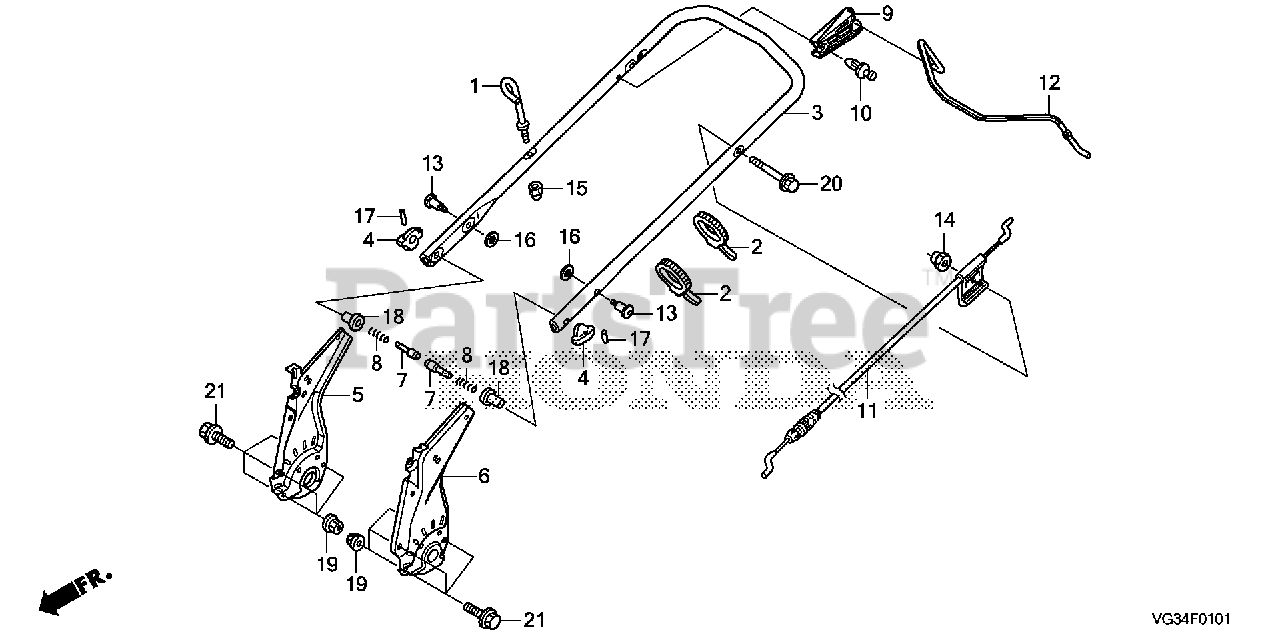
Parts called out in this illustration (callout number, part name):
1	GUIDE, ROPE
2	TIE, CABLE (157.5MM)
3	PIPE, HANDLE *NH105* (MAT BLACK)
4	GRIP, HANDLE JOINT *NH164* (GRIP GRAY)
5	STAY, R. HANDLE
6	STAY, L. HANDLE
7	PIN (8MM)
8	SPRING, HANDLE ADJUSTING
9	STOPPER, LEVER
11	CABLE, BRAKE
12	LEVER, BRAKE *NH105* (MAT BLACK)
13	BOLT, SPECIAL (8X32)
14	NUT, NYLON LOCK (6MM)
15	NUT, NYLON LOCK (6MM)
16	WASHER (25MM)
17	PIN, COILED (2X12)
18	COLLAR, HANDLE HEIGHT ADJUSTING
19	NUT, FLANGE (8MM)
20	BOLT, FLANGE (6X45)
21	BOLT, FLANGE (8X16)
